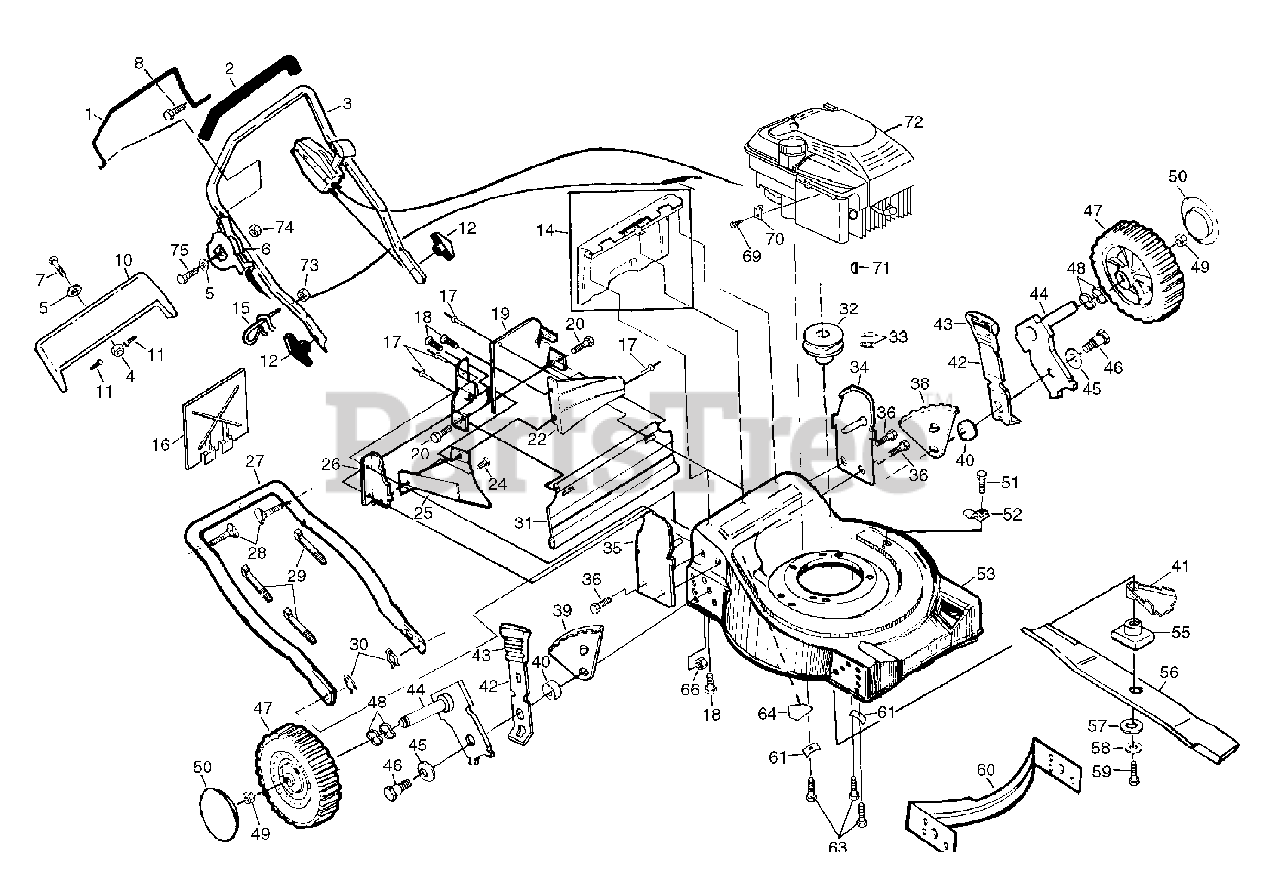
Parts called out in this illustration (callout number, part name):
1	Control Bar
2	Handle Grip
3	Upper Handle
4	Locknut 1/4-20
6	Throttle Control
7	Machine Screw 1/4-20 x 1
10	Trim Plate
11	Self-tapping Screw #10-24 x 5/8
12	Handle Knob
14	Rear Door Asm.
15	Rope Guide
16	Mulcher Plate
18	Hex Tapping Screw 1/4-20 x 1/2
19	Back Plate
20	Hinge Screw
22	Rear Baffle
24	Hex Head Screw #10-24 x 1/2
25	Discharge Baffle
26	Side Baffle
27	Lower Handle
28	Handle Bolt
29	Wire Tie
30	Hairpin Cotter
31	Rear Skirt
32	Engine Pulley
33	Set Screw 1/4-20 x 5/16
34	Handle Bracket Assembly (Left)
35	Handle Bracket Assembly (Right)
36	Thread Cutting Screw 5/16-18 x 3/4
38	Wheel Adjusting Bracket (Left Rear)
39	Wheel Adjusting Bracket (Right Rear)
40	Spacer
41	Shield Debris
42	Selector Spring
43	Selector Knob
44	Axle Arm Assembly
45	Belleville Washer
46	Shoulder Bolt 3/8-16
47	Wheel & Tire Assembly
48	Wave Washer
49	Hex Nut
51	Hex Washer Head Screw #10-24 x 1/2
52	Guide Clip
53	Lawn Mower Housing
55	Blade Adapter
57	Hardened Washer
58	Helical Lockwasher 3/8
59	Hex Head Screw 3/8-24 x 1-3/8
60	Front Baffle
61	Engine Washer
63	Hex Head Thread Rolling Screw 3/8-16 x 1
64	Danger Decal
66	Locknut 3/8-16
69	Thread Rolling Screw #10-32 x 5/8
70	Cable Clamp
71	Hi-Pro Key #HP-505
73	Locknut Keps 1/4-20
74	Hex Locknut 1/2-20 CAD
75	Screw 1/4-20 x 1.75
